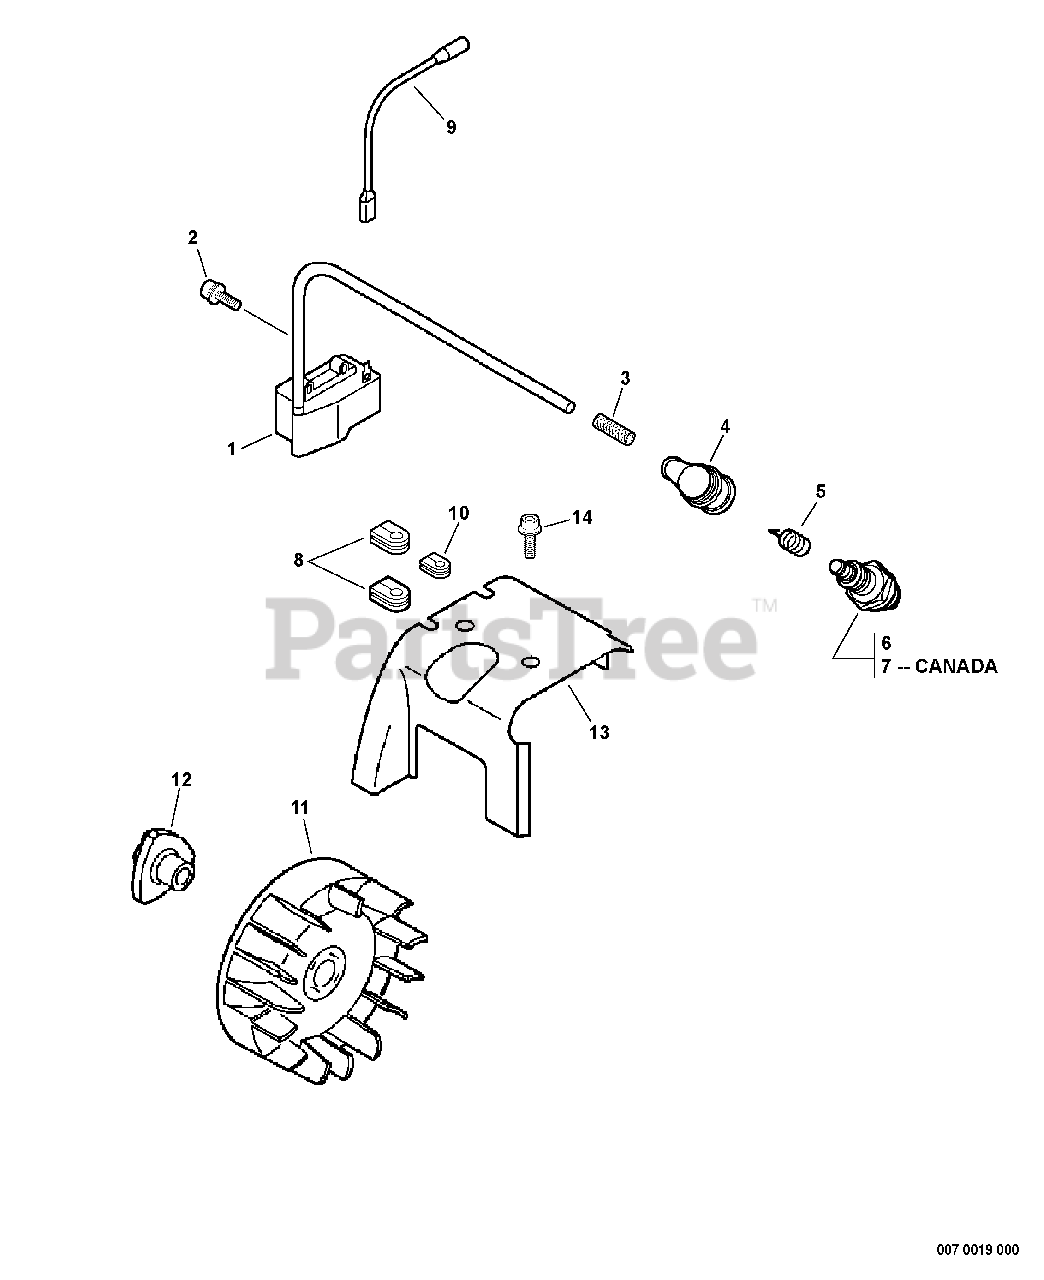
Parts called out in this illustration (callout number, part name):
1	COIL, IGNITION
2	SCREW - 4X20
3	INSULATOR
4	CAP, SPARK PLUG
5	TERMINAL, SPARK PLUG CAP
6	SPARK PLUG -- BPM-8Y
7	SPARK PLUG -- BPMR-8Y
9	LEAD - IGNITION
11	FLYWHEEL
12	HUB, FAN
13	SHIELD, CYLINDER
14	SCREW - 5X8
